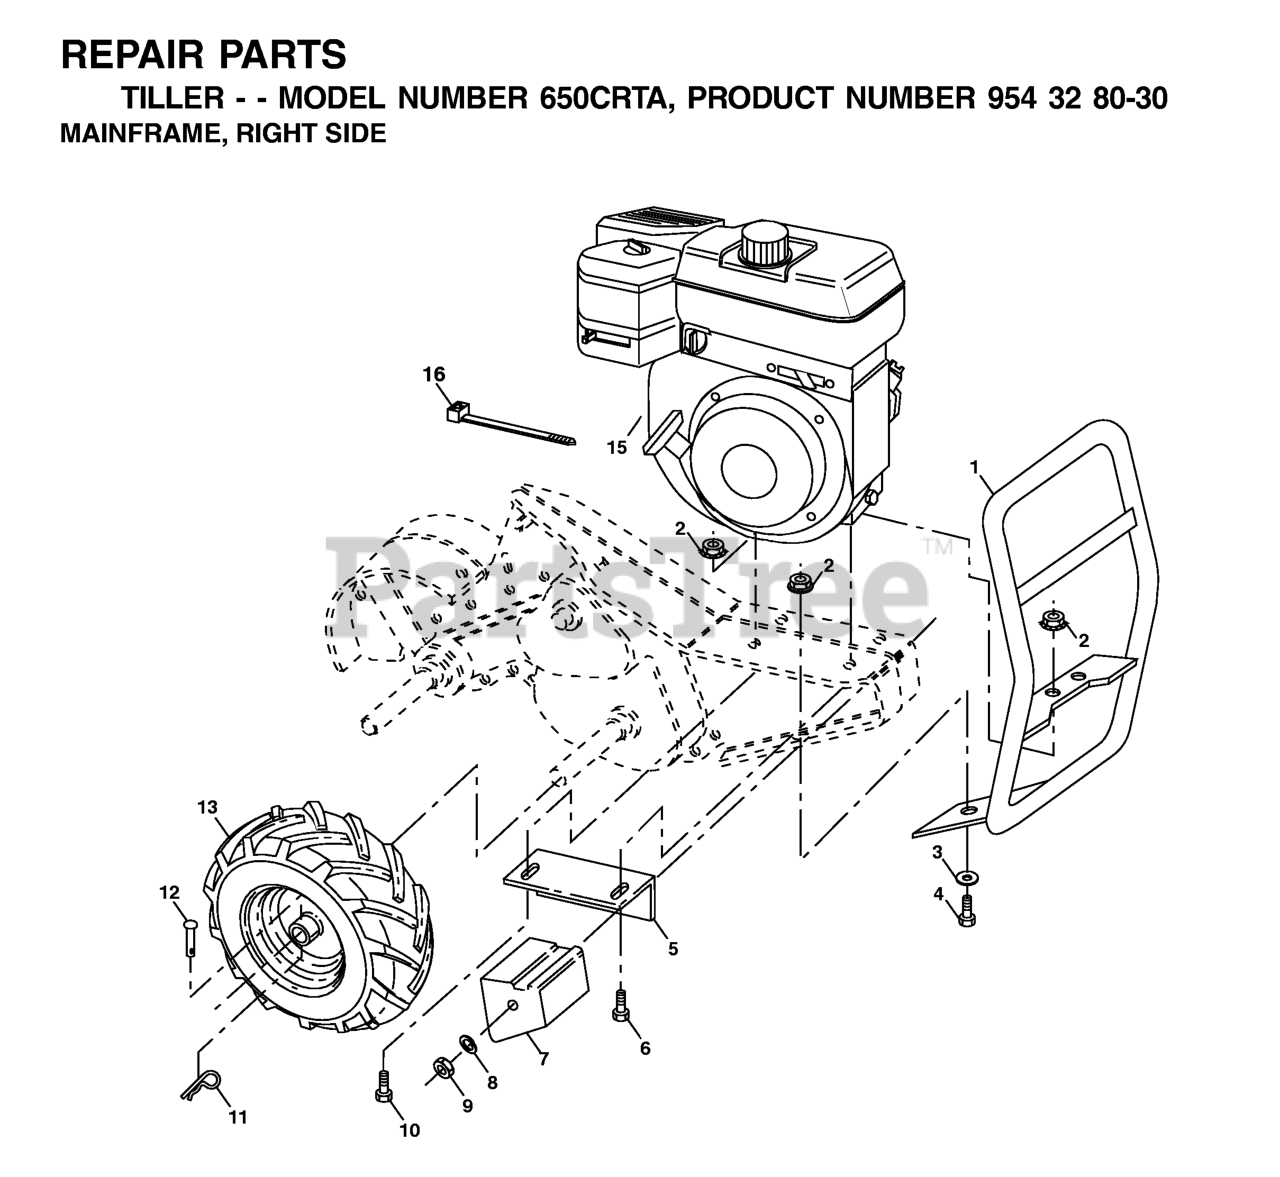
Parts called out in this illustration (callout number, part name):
1	BUMPER
2	LOCKNUT-FLANGE 5/16-18
3	WASHER
4	BOLT
5	DNO BRACKET RH CRT
6	Bolt Fin Hex 5/16 - 18 Unc x 2 Gr. 2
7	COUNTERWEIGHT, RH
8	WASHER, LOCK 3/8
9	NUT.HEX.3/8-16UNC
10	BOLT
11	RETAINER M
12	RIVET,DRILLED
13	TIRE.16X4-8.CHEVRON.TILLER
16	TIE GUIDE
532124366	RIM
532124718	VALVE STEM LT
